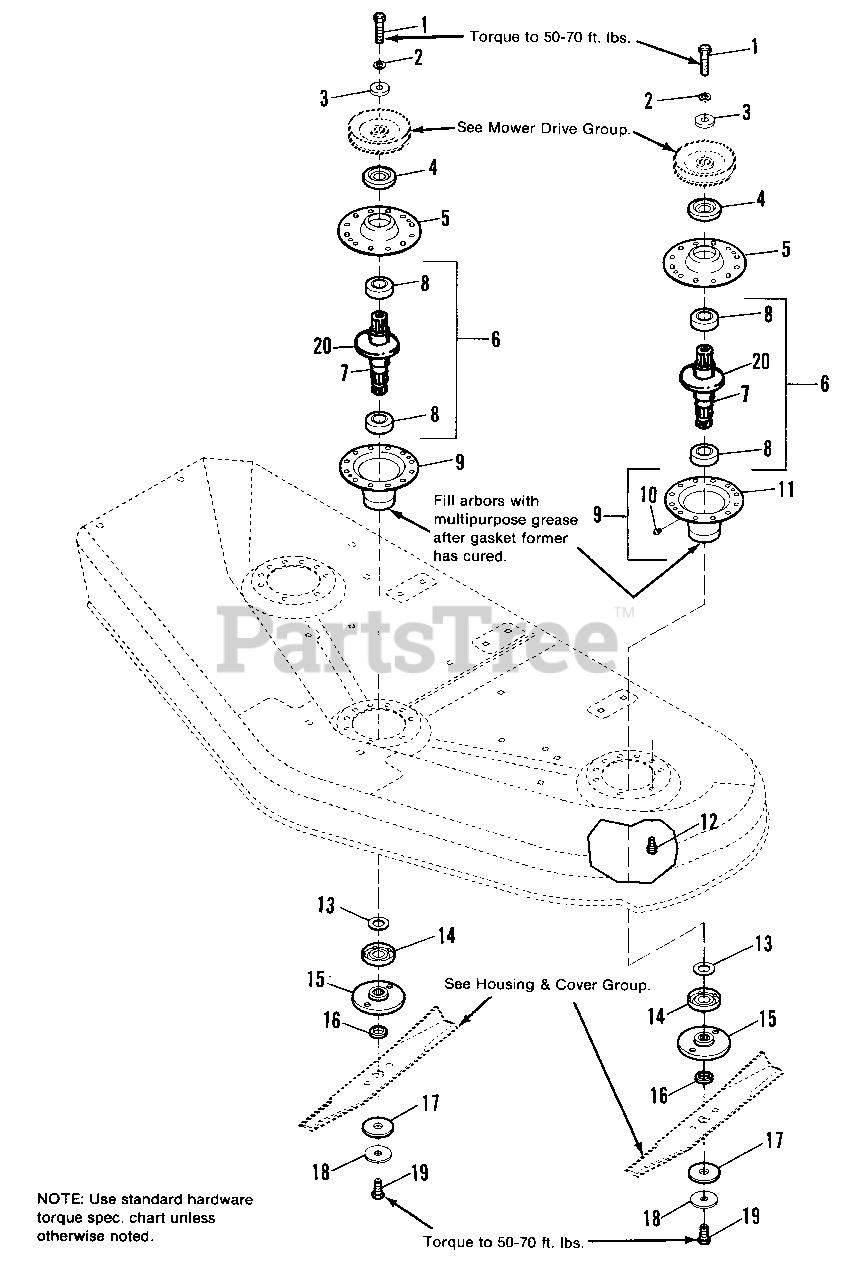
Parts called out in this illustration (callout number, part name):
1	CAPSCREW, Hex, 7/16-14 x 1-3/4
2	LOCKWASHER, 7/16
3	WASHER, 7/16
4	SHIELD, Bearing Upper, Arbor
5	HOUSING, Top
6	SHAFT & BEARING ASSY., (Incl. Ref. Nos. 7 & 8)
7	SHAFT, Arbor
8	BEARING ASSY.
9	HOUSING ASSY., Arbor Bottom (Incl. Ref. Nos. 10-11)
10	FITTING, Grease
12	SCREW, Taptite, 5/16-18 x 3/4
13	WASHER, Shim
14	SHIELD, Grass
15	ADAPTOR, Blade
16	COLLAR, Mower Arbor
17	WASHER, Spline
18	WASHER, Spring
19	CAPSCREW, Hex, 7/16-14 x 1
20	GASKET, Foam
